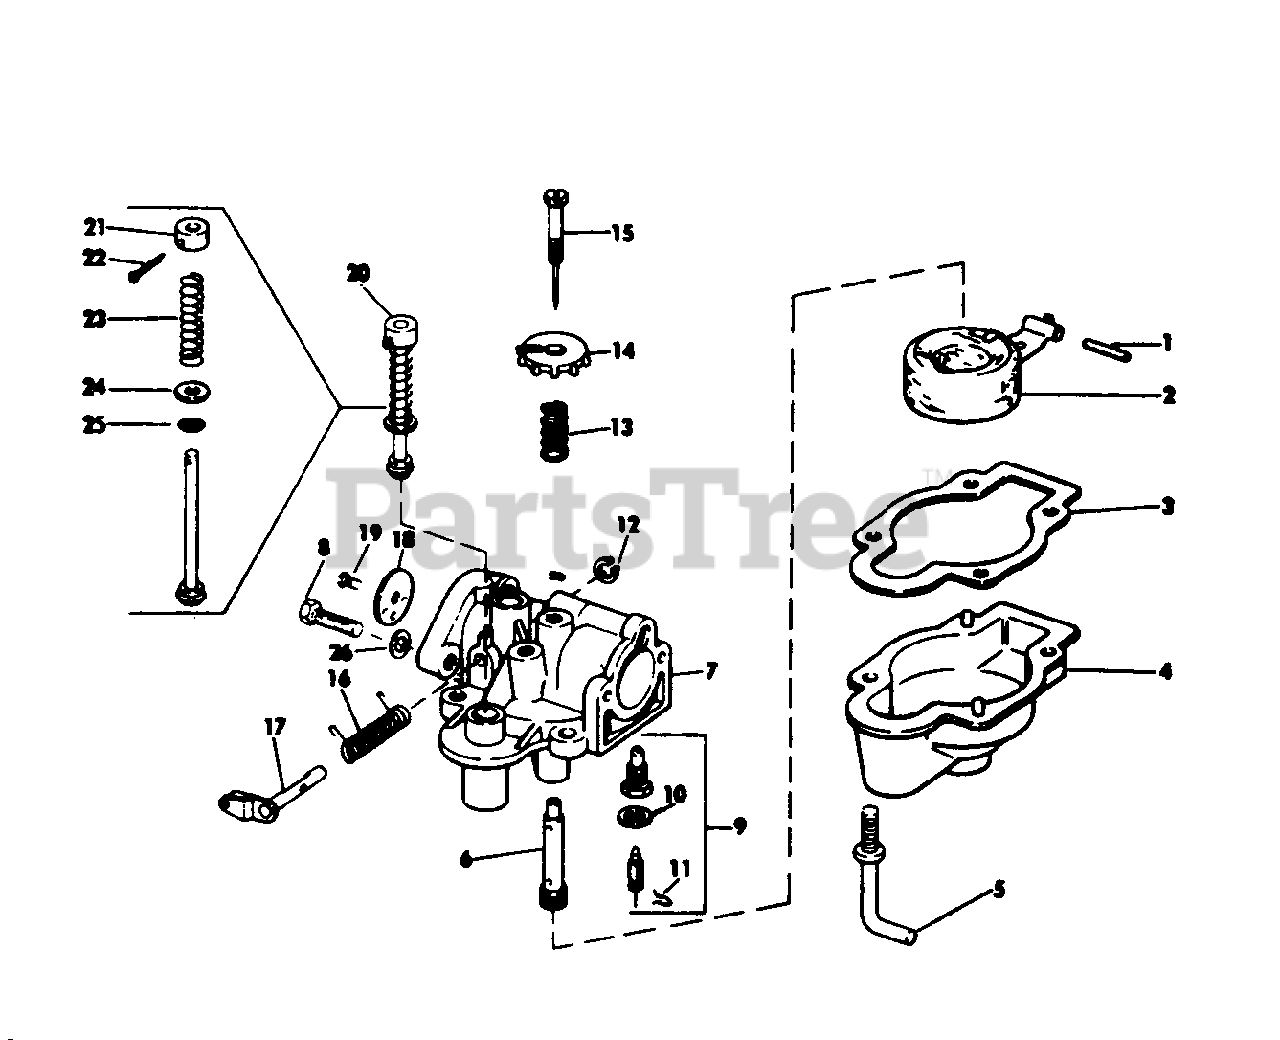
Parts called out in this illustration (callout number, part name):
1	Pin-Float Arm Hinge
2	Float and Arm Assy.
3	Gasket-Float Chamber
4	Chamber-Float
5	Screw-Float Chamber
7	Carburetor Body Assy.
9	Float Valve and Seat
10	Washer-Float Valve Seat
11	Clip
12	Grip Ring
13	Spring-Needle Adj.
14	Knob-Needle Adj.
15	Needle Assy.
16	Spring-Throttle
17	Throttle Shaft and Lever Assy.
18	Disc-Throttle
19	Scr.-Throttle Shaft Disc.
20	Primer Assembly
21	Knob Primer
22	Cotter Pin
23	Spring Compression
24	Washer-Plain
25	"O" Ring
